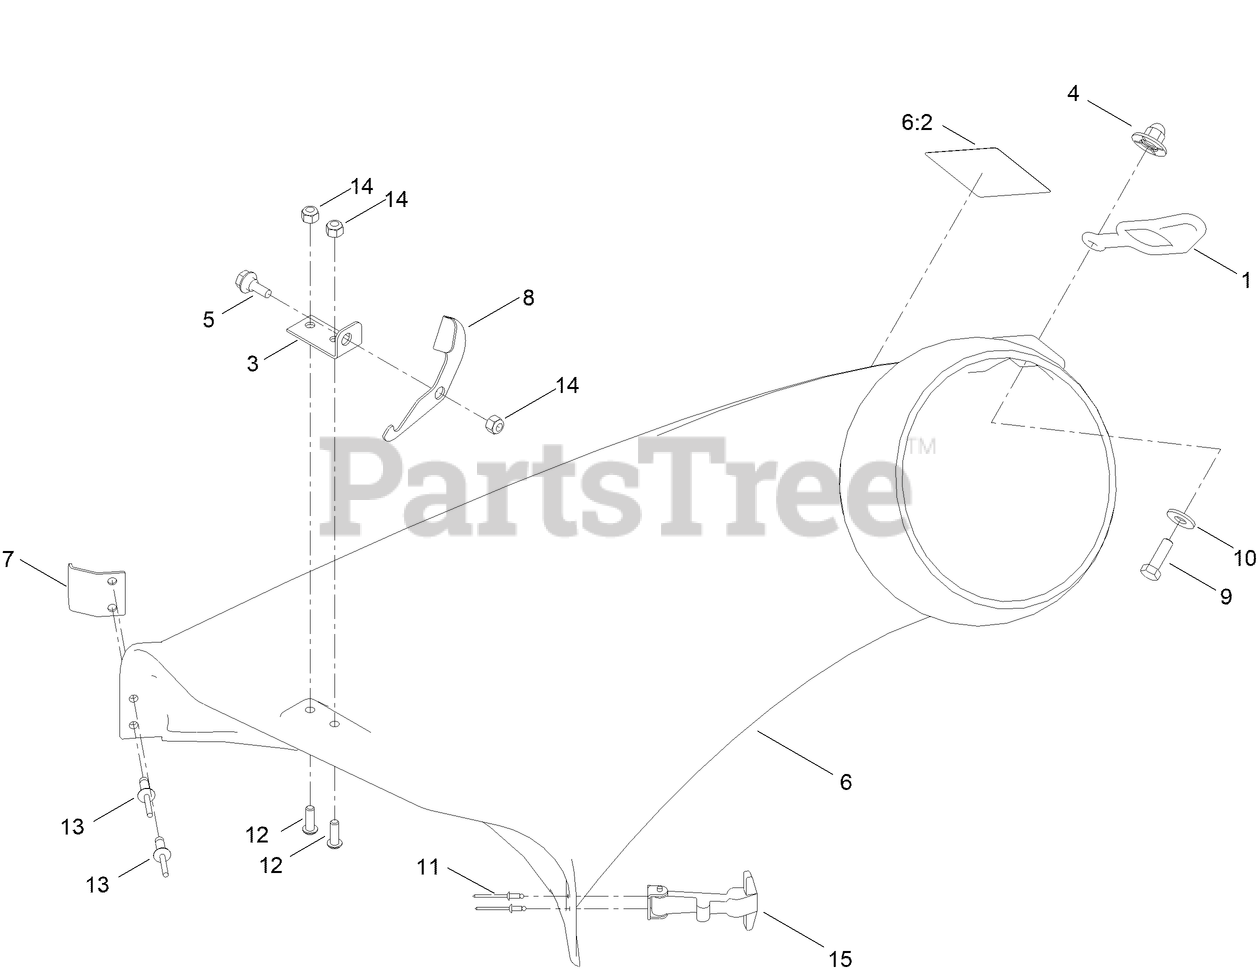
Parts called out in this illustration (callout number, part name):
1	RETAINER-DUCT
3	PLATE-PIVOT
4	NUT-IMPELLER
5	SCREW-SHOULDER,HWH
6	42 INCH BAGGER BOOT
6:2	DECAL-DANGER
7	BRACKET-ELBOW
9	SCREW-HH
10	WASHER-FLAT
11	RIVET-POP
12	SCREW-HSBH
13	RIVET-BLIND
14	NUT-LOCK, NI
15	HANDLE ASM
